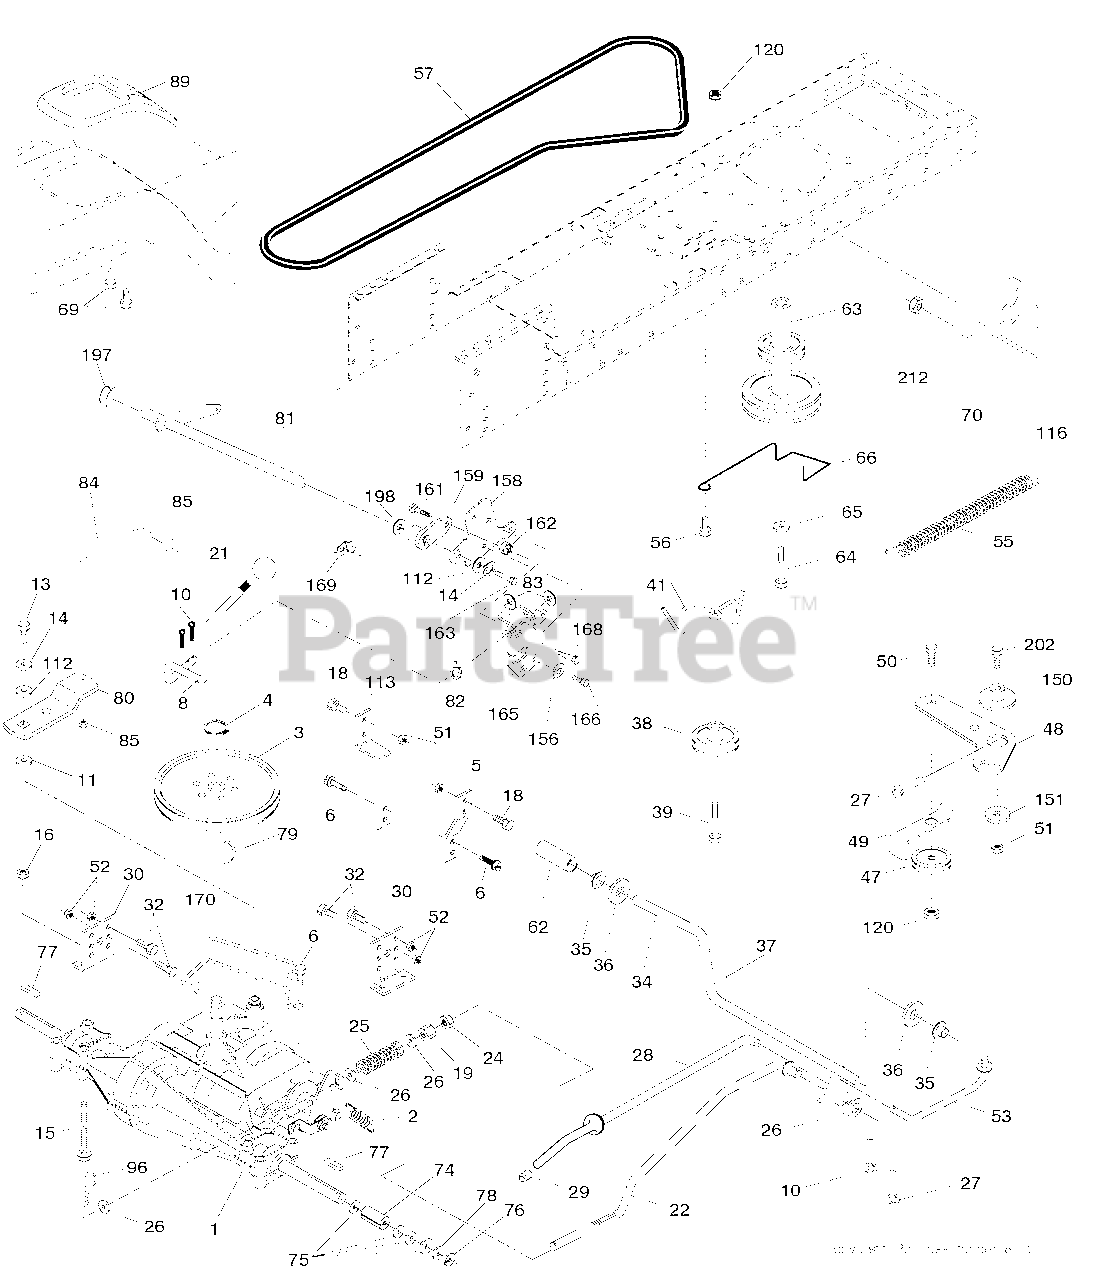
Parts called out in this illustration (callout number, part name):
2	Spring Return Brake T/a Zinc
3	Pulley Transaxle 18" Tires
4	Ring Retainer # 5100-62
5	Strap Torque 30 Degrees
6	Screw 5/16-18 x 3/4
8	Rod Shift Fender Adjust Lt
10	Pin Cotter 1/8 x 1 Cad
11	Washer Plate Shf 388 Sq Hole
13	Bolt 1/4-28 unf Gr. 8 w/Patch
14	Washer Lock Hvy Helical
15	Bolt Hex FLGHD 5/16-18 Gr. 5
16	Nut Lock Hex w/ins 5/16-18
18	Bolt, Fin Hex 3/8-16 unc x 1 Gr. 5
19	Nut Lock 3/8-16 unc
21	Knob
22	Rod Brake Blk Zinc 26 840
24	Nut Hex Jam 3/8-16 unc
25	Spring Rod Brake 2 00 Zinc
26	Washer 13/32 x 13/16 x 16 Ga.
27	Pin Cotter 1/8 x 3/4 Cad
28	Rod Brake Parking LT/YT
29	Cap Brake Parking
30	Bracket Mtg Transaxle
32	Bolt Hex Hd 5/16-18 unc x 3/4
34	Shaft Asm Pedal Foot
35	Bearing Nylon Blk 629 Id
36	Washer 21/32 x 1 x 16 Ga.
37	Pin Roll 3/16 x 1"
38	Pulley Composite Flat
39	Bolt RDHD 3/8-16 unc x 2-3/4 Gr. 5
41	Keeper Belt Flat Idler
47	Pulley Idler V Groove Plastic
48	Bellcrank Asm
49	Retainer Belt Style Spring
50	Bolt Carr. Sh. 3/8-16 x 1-1/2 Gr. 5
51	Nut Crownlock 3/8-16 unc
52	Nut Crownlock 5/16-18 unc
53	Link Clutch
55	Spring Return Clutch 6 75
56	Screw 3/8-16 x 1-1/4
57	V-Belt Ground Drive
62	Cover Pedal Blk Round
63	Engine Pulley
64	Bolt Hex
65	Washer Lock Hvy Hlcl Spr 7/16
66	Keeper Belt Engine Foolproof
69	Screw Hex wsh HiLo 1/4 x 1/2 unc
70	Guide Belt Mower Drive RH
74	Spacer Axle
75	Washer 25/32 x 1 1/4 x 16 Ga.
76	E-ring #5133-75
77	Key Square 2 0 x 1845/ 1865
78	Washer 25/32 x 1-5/8 x 16 Ga.
79	Key Woodruff #9 3/16 x 3/4
80	Arm Shift
81	Shaft Asm Cross Tapered PMST/
82	Spring Torsion T/a
83	Washer 17/32 x 3/4 x 16 Ga.
84	Link Transaxle
85	Nut Lock Center 1/4 - 28 FNTHD
89	Console Shift STLT
96	Retainer Spring 1"
112	Washer 9/32 x 3/4 x 10 Ga.
113	Strap Torque LT
116	Bolt Rdhd Sq Neck 3/8-16 x 1
120	Nut Lock Flg. 3/8-16 unc
150	Spacer Retainer
151	Washer 13/32 x 2 x 10
156	Washer Srrted 5/16ID x 1.125
158	Bracket Shift Mount
159	Hub Tapered Flange Shift Lt
161	Bolt Rdhd Sqnk 1/4-20 x 3/4
162	Nut Crownlock 1/4-20 unc
163	Bolt Hex Fin 1/4-20 unc x 1 Gr. 5
165	Bracket Pivot Lever
166	Screw 5/16-18 x 5/8
168	Bolt Shoulder 5/16-18 x .561
169	Plate Fastening
170	Keeper Belt Transaxle Gear
197	Nyliner Snap-In
198	Washer Nyliner
202	Bolt RdHd 3/8-16 unc x 1-3/4 Gr.
212	Nut Hexflange Lock
